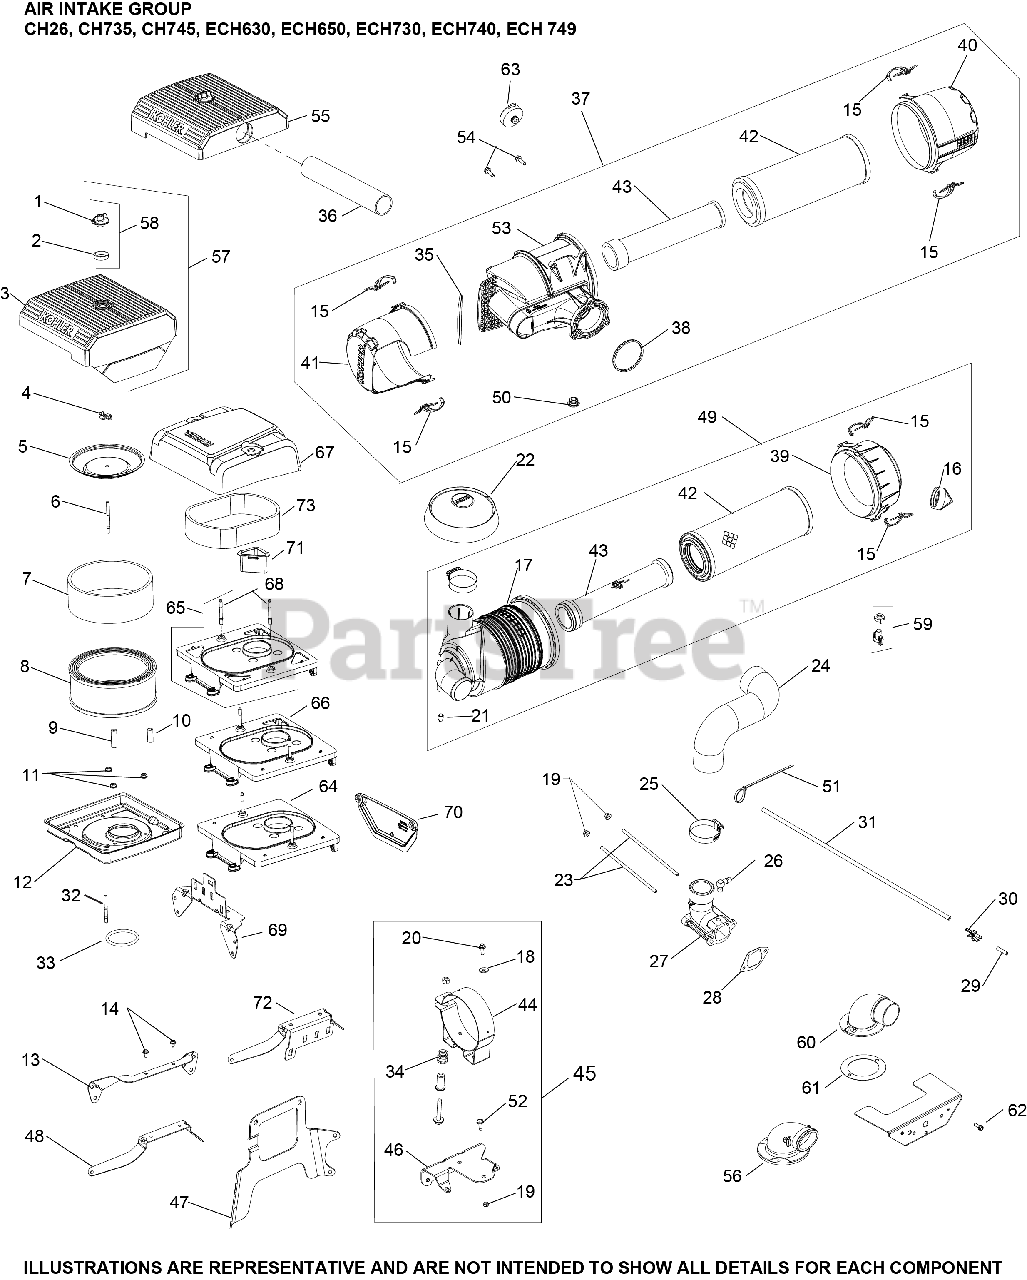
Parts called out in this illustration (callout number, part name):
1	KNOB, COVER
3	COVER, AIR CLEANER
4	NUT, WING
5	COVER, INNER AIR CLEANER
7	ELEMENT, PRECLEANER (LOW)
8	ELEMENT, AIR CLEANER - Also available Retail Packaged 47 883 03-S1 Air Filter Kit
11	NUT, FLG M6X1.0
12	BASE, AIR CLEANER
13	BRACKET, AIR CLEANER BASE
14	SCREW, THREAD FORMING
29	CAP, MASKING
30	CONNECTOR, EVAPORATIVE
32	STUD, LOW PROFILE A/C
33	O-RING, AIR CLEANER BASE
36	HOSE, HEATER
55	COVER, AIR CLEANER
57	KIT, AIR CLEANER COVER
58	KIT, KNOB W/SEAL
62	SCREW, HI-LOW
